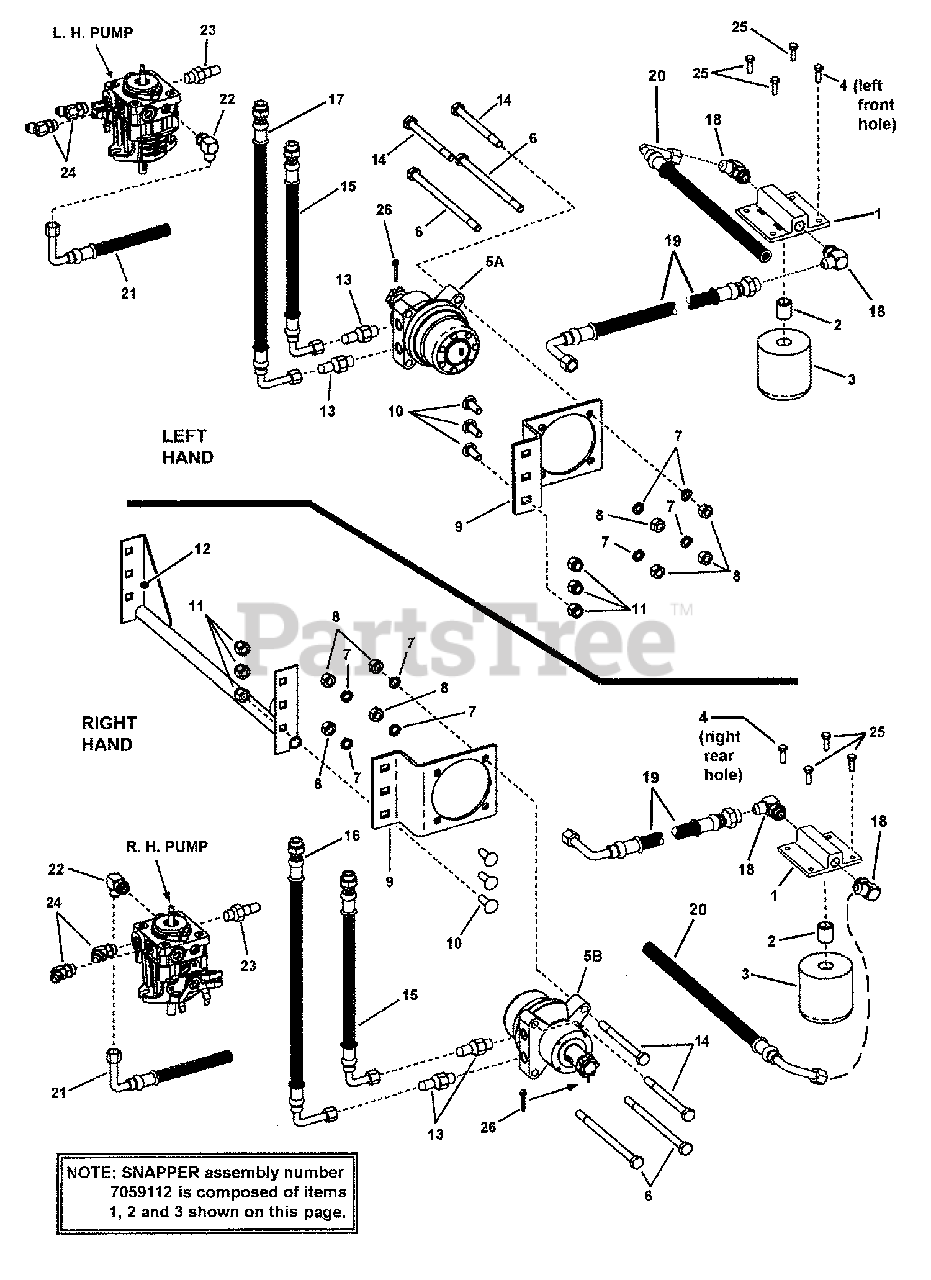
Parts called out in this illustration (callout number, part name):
1	MOUNT, Oil Filter
2	FITTING, Straight 1-12 UNF Thread
3	FILTER, Oil
4	SCREW, 3/8-16 x 3/4" Hex Washer Self-Tap
5A	MOTOR, Hydraulic, Left Hand
5B	MOTOR, Hydraulic, Right Hand
6	BOLT, 1/2-13 x 6" Hex Head Cap GR 5
7	WASHER, 1/2" Split Lock
8	NUT, 1/2-13 HEX
9	PLATE, Mounting
10	BOLT, 1/2-13 x 1-1/2" Square Neck Carriage, GR 5
11	NUT, 1/2-13 Hex Nyloc
12	WELDMENT, Rear Crossbrace
13	CONNECTOR, Straight Hydraulic (Parker # 8-10 F5OLO-S)
14	BOLT, 1/2-13 x 3-3/4" Hex Head Cap
15	HOSE, 15-1/2" Hydraulic (Parker # F436JCJ9080808-15.50)
16	HOSE, 19-1/2" (Parker # F436BKJCJ5080808-19.5)
17	HOSE, 17-1/2" Hydraulic (Parker # F436BKJCJ5080808-17.5)
18	CONNECTOR, 90-Degree Hydraulic (Parker # 8 C5OLO-S)
19	HOSE, 18-1/2" (Parker R836BKJCJ9090808-18.5)
20	HOSE, 12-1/4" (Parker # R836BKJ9NR080008-12.5)
21	HOSE, 6-1/2" (Parker # R836BKJ9NR080008-6.5
22	CONNECTOR, 90-Degree Hydraulic (Parker # 8-6 C5OLO-S
23	CONNECTOR, Straight Hydraulic (Parker # 8-6 F5OLO-S)
24	CONNECTOR, 45-Degree Hydraulic (Parker # V5OLO-S)
25	SCREW, 5/16-18 x 3/4" Hex Washer Self-Tap
26	PIN, 9/64 x 1-1/2" Cotter
